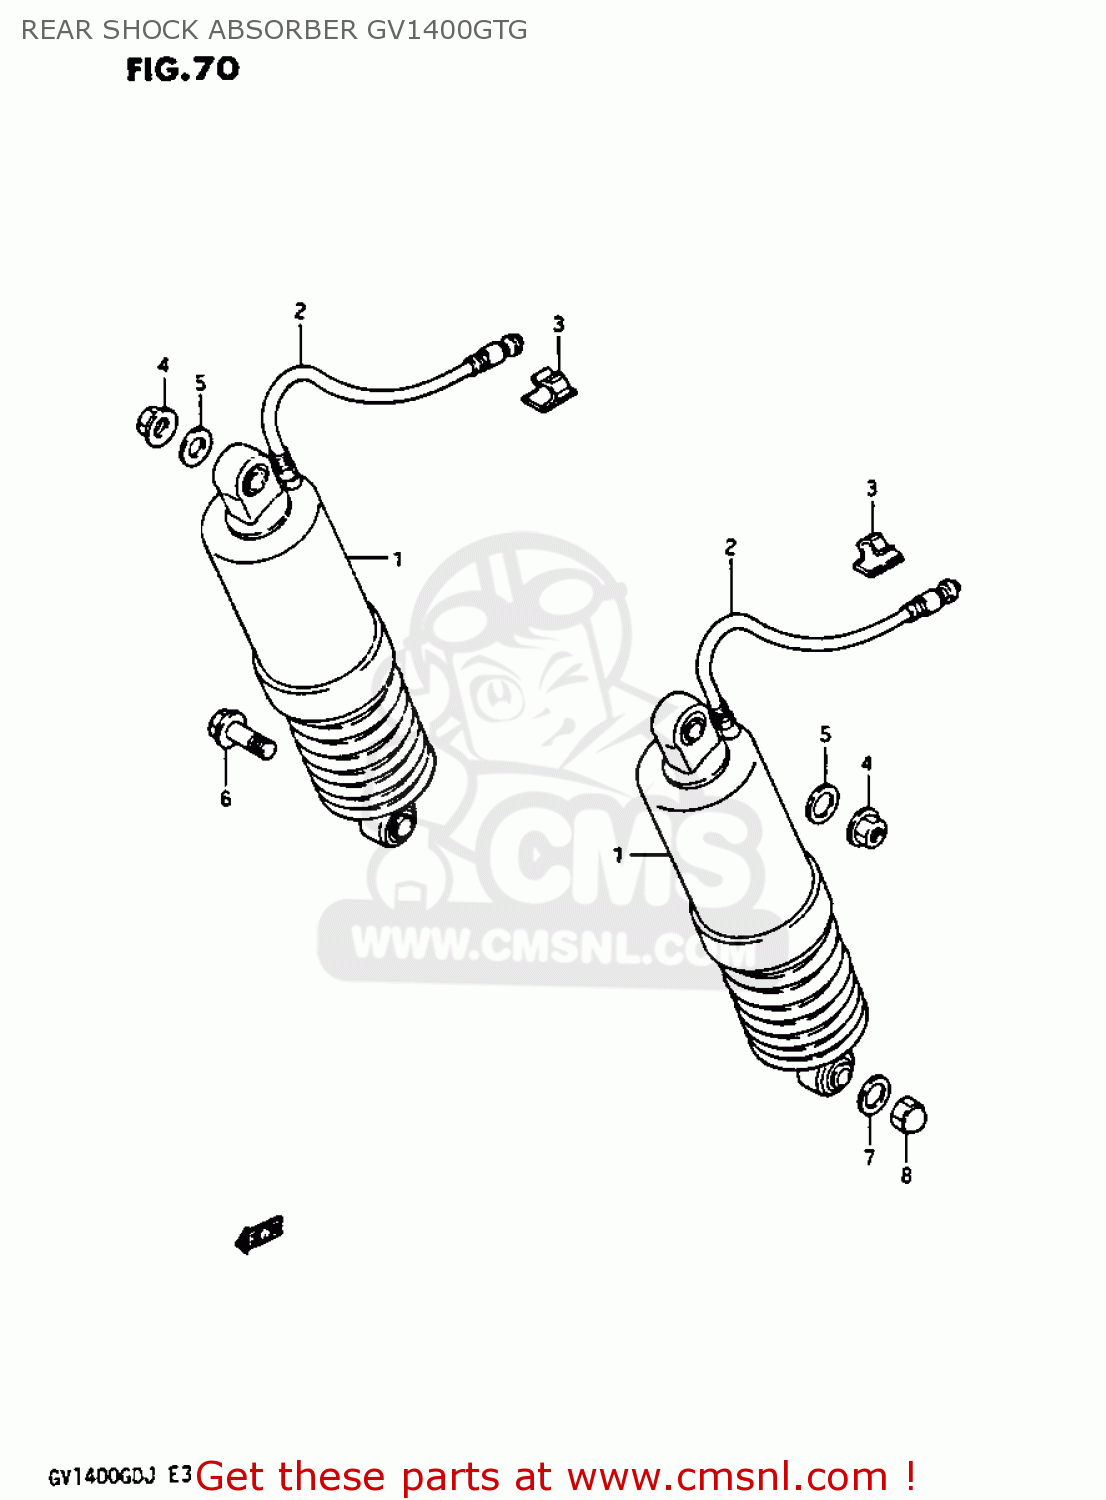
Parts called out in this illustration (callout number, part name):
1	ABSORBER ASSEMBLY,REAR SHOCK
2	HOSE,AIR VALVE
3	CLAMP
4	NUT
5	WASHER
6	BOLT 2X33
7	WASHER
8	NUT
